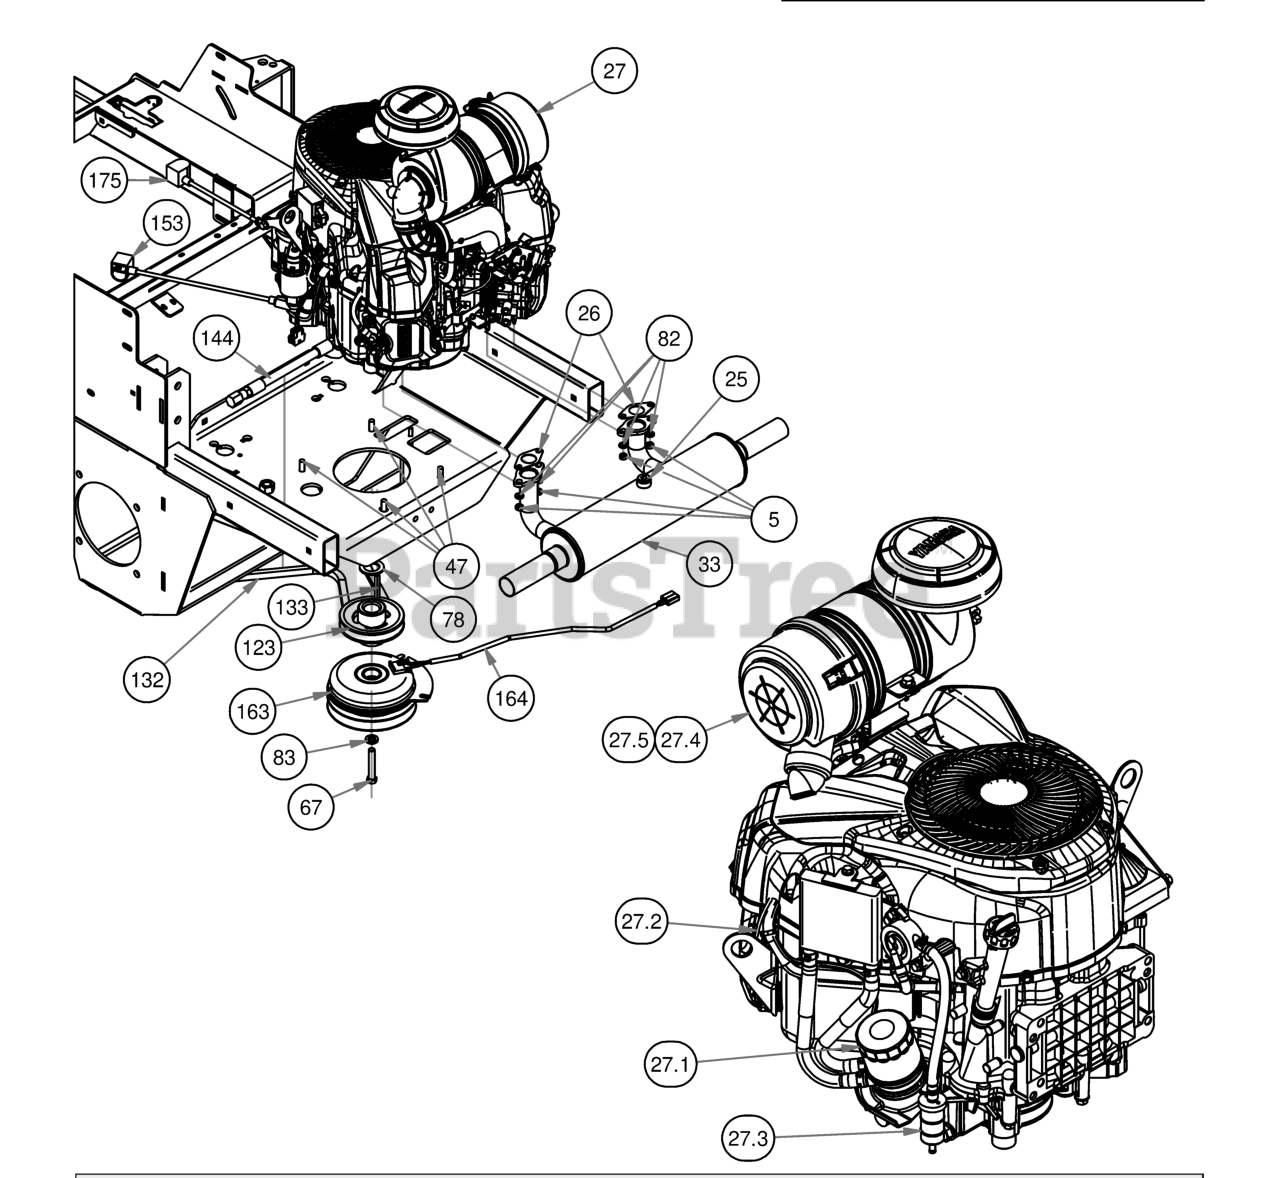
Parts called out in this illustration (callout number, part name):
5	M8-1.25 Zinc Nut
25	O2 Sensor Plug
26	Exhaust Gasket for yamaha
27	Carbureted 27.5hp Yamaha Engine
27.1	Oil Filter
27.2	Yamaha Spark Plug
27.3	Yamaha Fuel Filter
27.4	Canister Air Filter- Outer
27.5	Canister Air Filter- Inner
33	Muffler for 27Hp Yamaha
47	3/8 x 1 1/8 bolt
67	7/16" x 2 1/2" Hex Bolt
78	1 1/8" Flat Spacer
82	5/16" Lock Washer
83	7/16" Lock Washer
123	4 3/4 Motor Pulley
132	2019 Rebel Pump Belt
133	1/4 x 2 Square key Stock
144	Oil drain Hose for Yamaha
153	14" Red Battery Cable-Base Outlaw
163	Clutch Assembly
164	Clutch Pigtail
165	2019 Rigid Frame
175	Starter Cable
